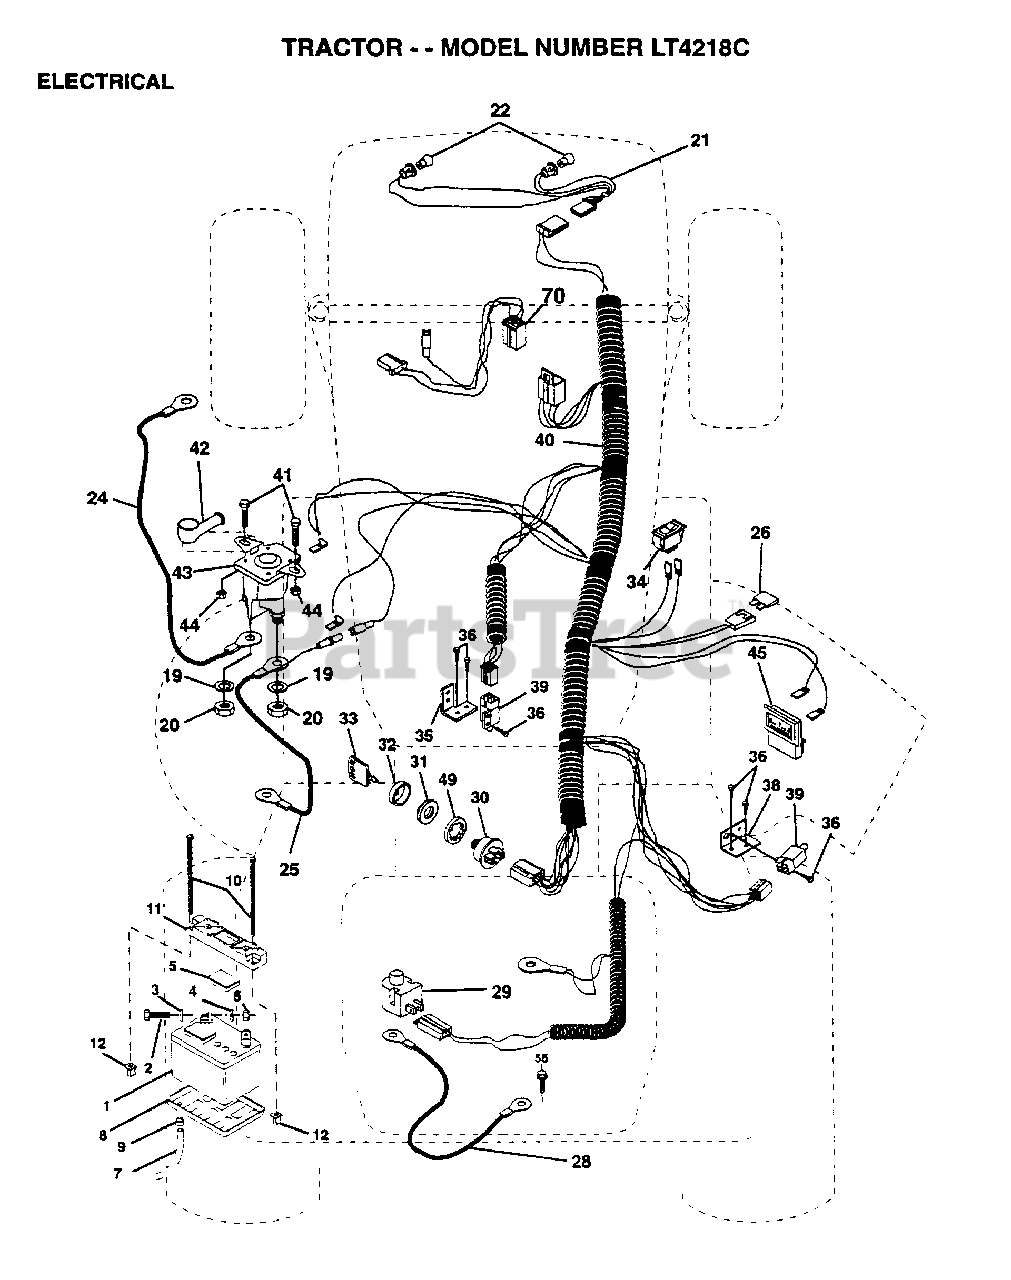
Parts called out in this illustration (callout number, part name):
2	BOLT LT
3	WASHER
4	LOCKWASHER
5	"CAP,BATTERY "
7	"DRAIN TU T, BATT"
8	"TRAY T, BATTERY"
9	HOSE CLAMP T
20	NUT
21	"HARNESS,LIGHT SOC"
22	HEADLAMP BULB
24	CABLE.6GA.22W/16W
25	"CABLE T, BATTERY"
26	FUSE HYT
28	CABLE.GRND.6GA.21
29	SWITCH SEAT
32	COVER KEY SWITCH
33	KEY MLD GEN DELTA
34	SWITCH LT
35	BRACKET LT
36	SCREW
38	BRACKET SWITCH IN
39	SWITCH INTERLOCKT
40	HARNESS.IGN.DASH.
41	BOLT.HX.1/4-20
44	NUT
49	LOCKWASHER
55	SCREW LT
70	HARNESS ENG DUAL
